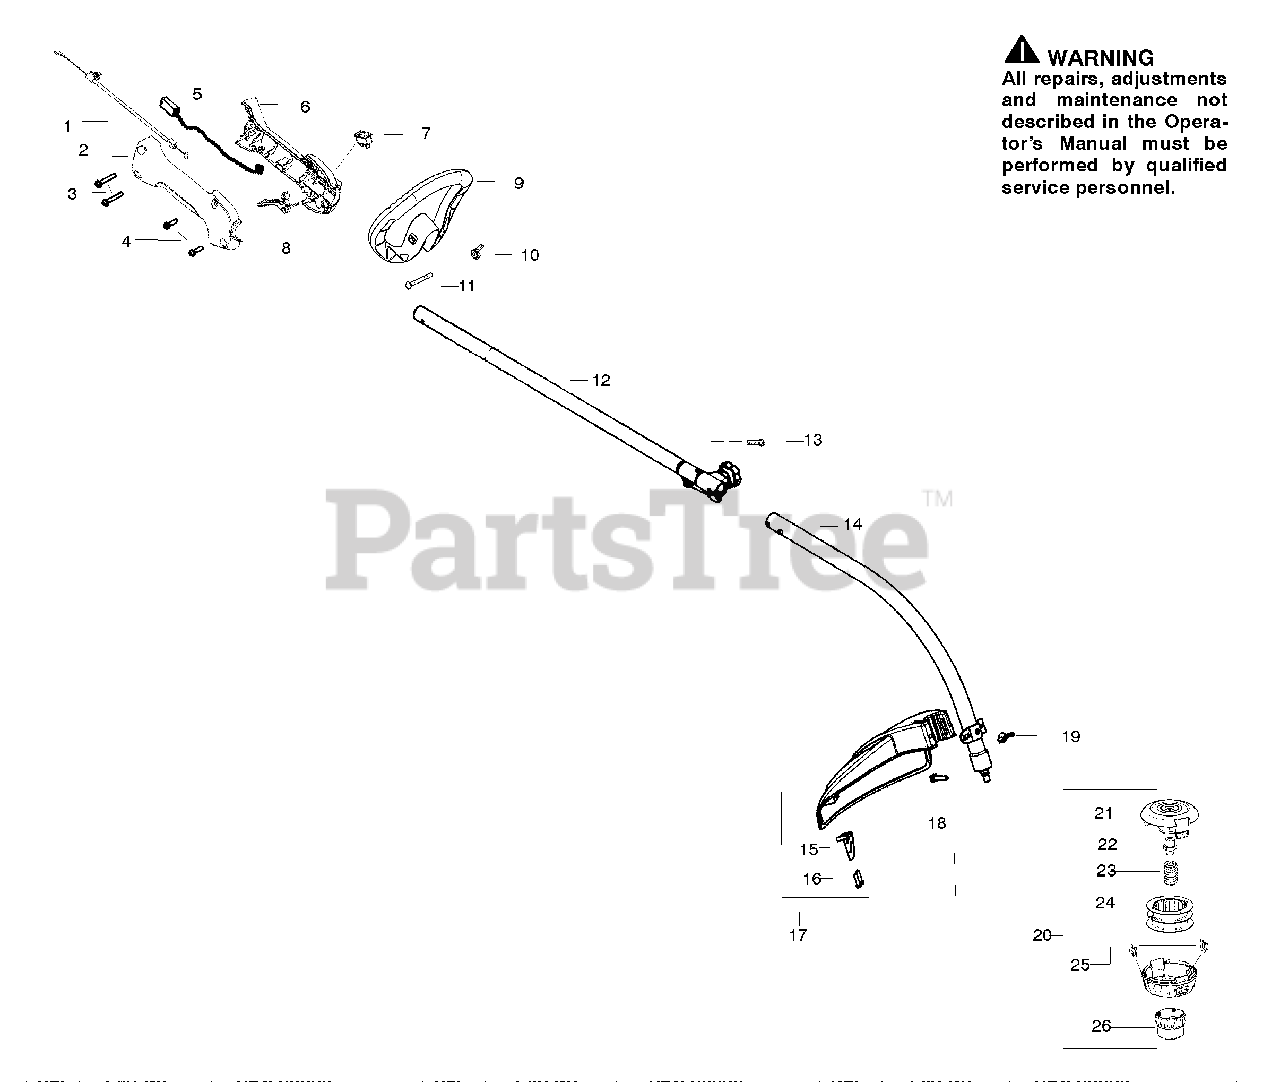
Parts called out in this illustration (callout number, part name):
1	Assy-Throttle Cable
2	Hsg.-Throttle
5	Assy.-Wire
6	Hsg. Throttle
7	Kit-Switch
8	Trigger-Throttle
9	Assy-Handle-Assist
10	Wingnut
12	Kit-Upper Shaft
14	Kit-Lower Shaft
15	Limiter-Line
17	Kit-Shield Assy.
19	Wingnut
20	Accy-TNG7
24	Assy-Wound Spool
25	Kit-Cover and Eyelet
